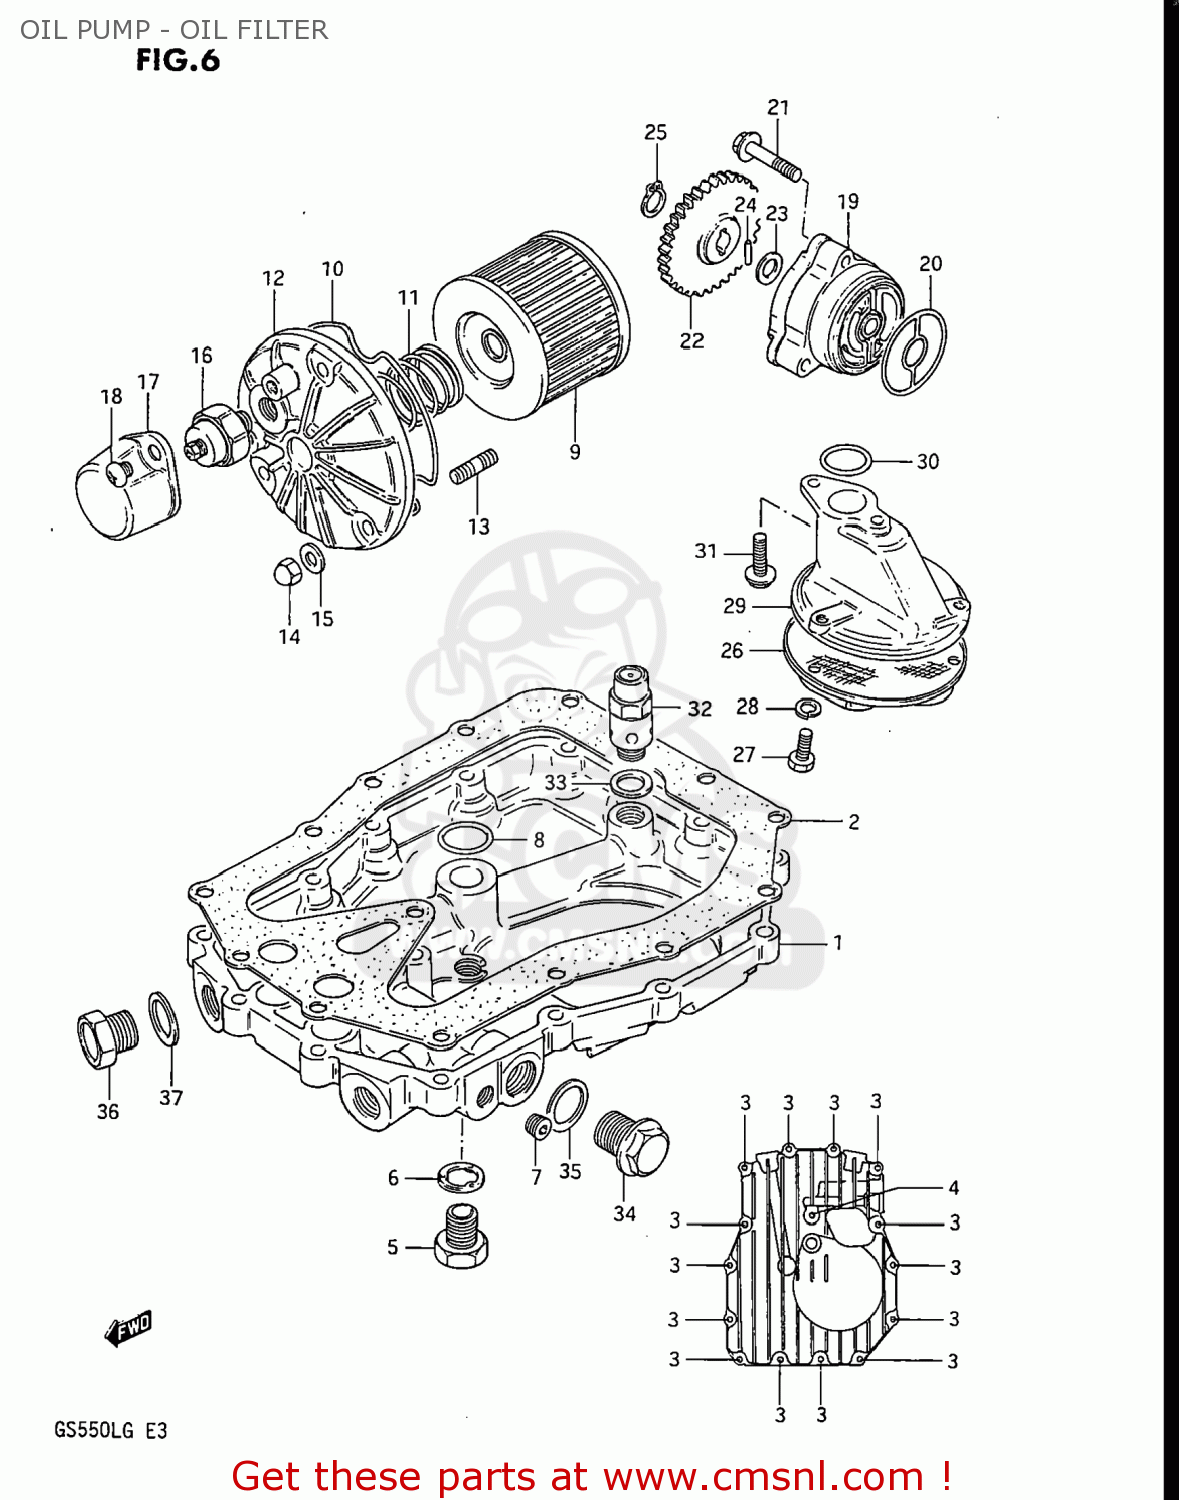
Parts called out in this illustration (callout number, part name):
1	PAN,OIL
2	GASKET,OIL PAN (MCA)
3	BOLT
4	BOLT 6X35
5	PLUG
6	GASKET(14X19.2X2) (NAS)
7	PLUG
8	O RING(D:3.2,ID:17.8)
9	FILTER ASSY,ENGINE OIL
10	O RING,OIL FILTER CHAMBER CAP
11	SPRING
12	CAP,ENGINE OIL FILTER
13	STUD 6X20
14	NUT 6MM
15	WASHER
16	SWITCH ASSEMBLY
17	COVER,OIL PRESSURE SWITCH
18	SCREW
19	PUMP ASSEMBLY,ENGINE OIL
20	O RING,OIL PUMP
21	BOLT(6X32)
22	GEAR,OIL PUMP DRIVEN
23	SHIM
24	PIN(4X15.8)
25	CIRCLIP
26	STRAINER,ENGINE OIL
27	BOLT
28	LOCK WASHER
29	PROTECTOR,OIL STRAINER
30	O RING(D:3.2,ID:17.8)
31	BOLT,REAR
32	REGULATOR ASSEMBLY,ENGINE
33	WASHER
34	PLUG
35	O RING(D:2.4,ID:16.8)
36	PLUG
37	GASKET(14X19.2X2) (NAS)
